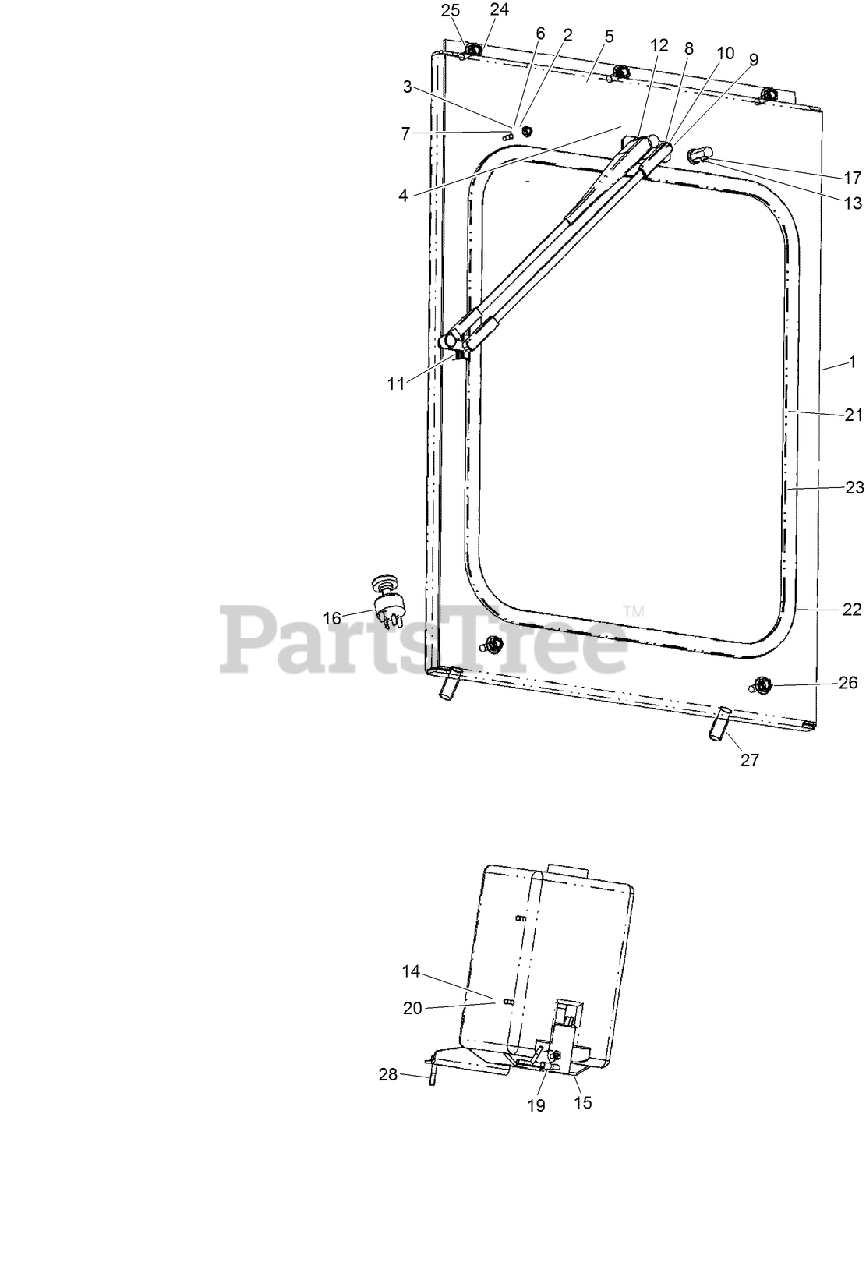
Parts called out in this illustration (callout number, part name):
1	WELDMENT - Front Windshield Frame
2	WASHER-FLAT
3	SPACER-13 mm (1/2 inch) long
4	MOTOR - Wiper, 12 Volt
5	COVER - Wiper
6	NUT, METRIC FLANGE PREVAILING - M6 Zinc
7	SCREW, METRIC FLANGE FULL - M6 x 50
8	ARMS - Wiper, w/Pantograph
9	SCREW-HWH
10	NUT - Prev Trq #10 GR8 ZND Insert
11	BLADE - 16 Wiper
12	SPACER - Pipe
13	NOZZLE - Washer, Spary
14	PLATE - Washer Bottle Mount
15	KIT - Reservoir
16	SWITCH-WIPER
17	CLAMP - Hose Type F #04
19	CONNECTOR - Tee, Barbed, 3/16
20	SCREW-HHF
21	GLASS - Front Windshield
22	SEAL - Front Window
23	LOCKING STRIP - Front Window
24	SCREW-FLANGE
25	NUT-FLANGE, NYLOCK
26	PLATE - Windshield Mount
27	SCREW-FLANGE
28	SCREW, METRIC FLANGE w/BODY - M6 x 30
